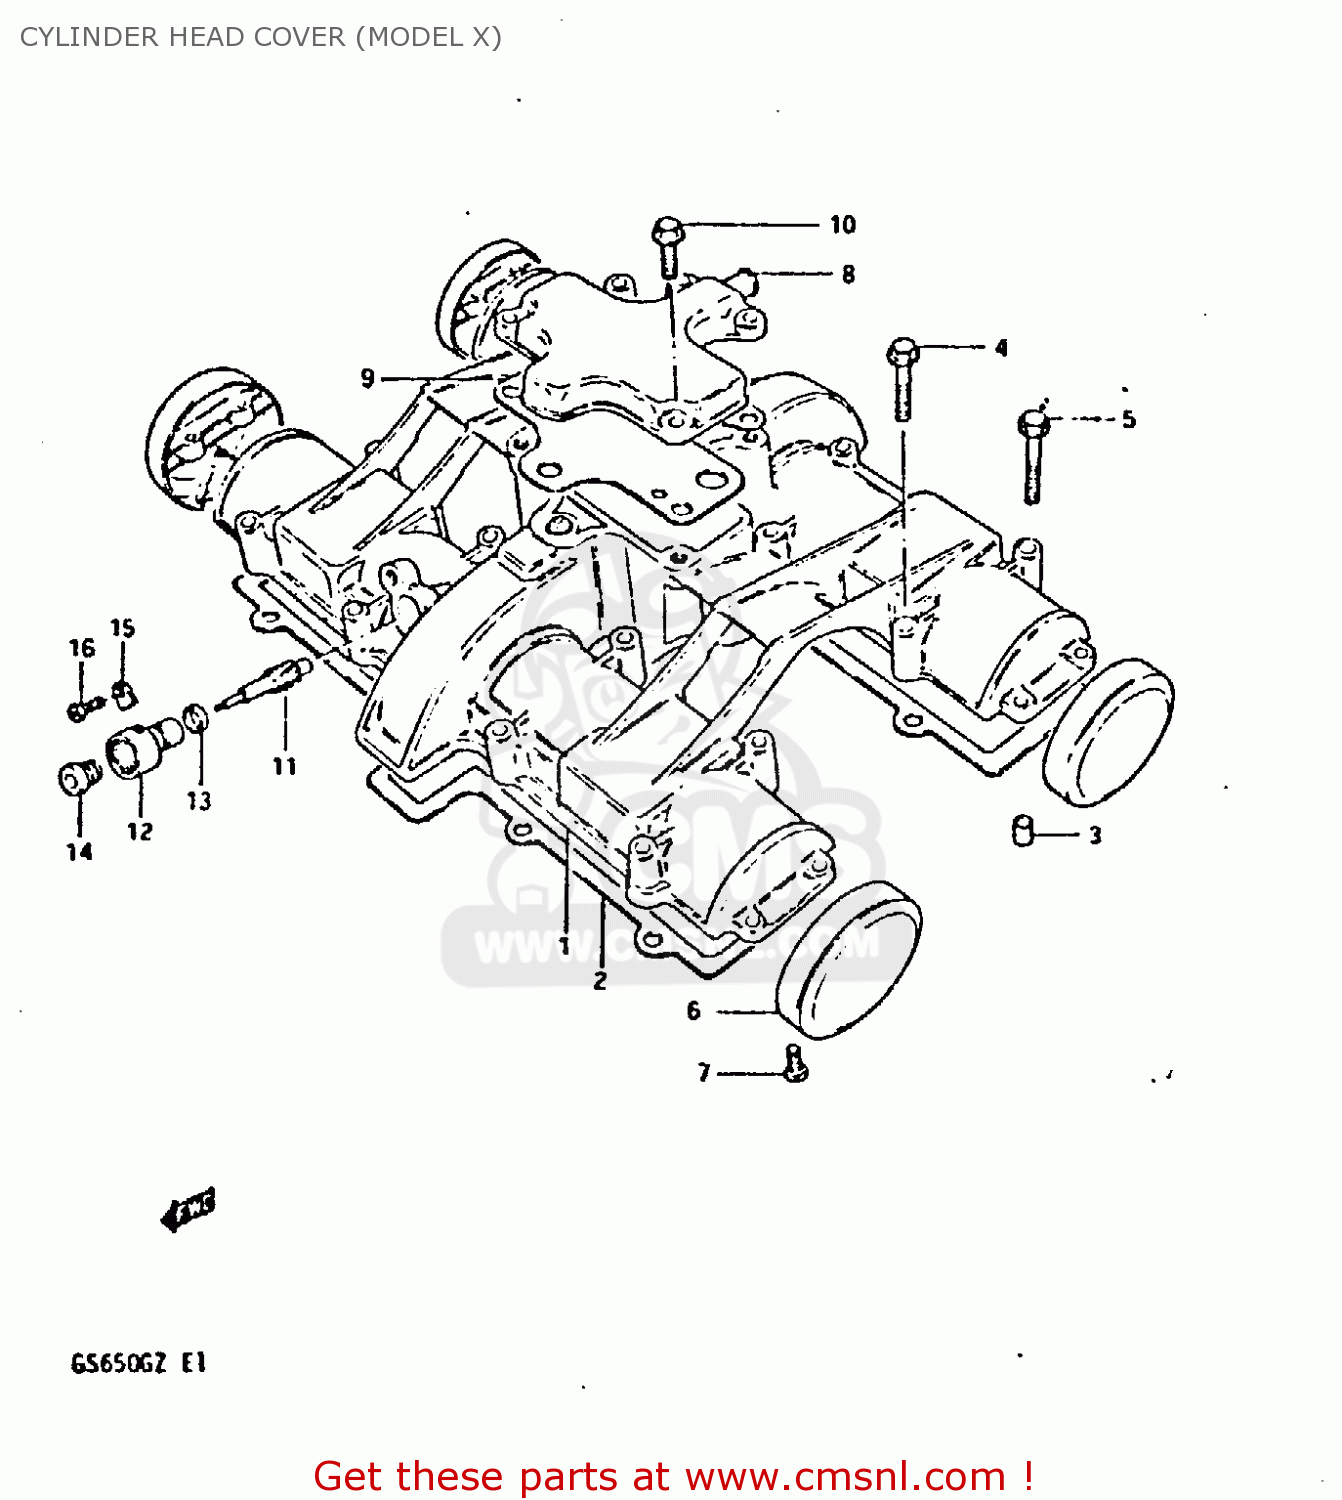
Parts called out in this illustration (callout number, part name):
1	COVER,CYLINDER HEAD
2	GASKET,CYLINDER HEAD COVER (MCA)
3	PIN(6.2X8X11)
4	BOLT
5	BOLT,UNDER
6	CAP,CYLINDER HEAD COVER
7	SCREW
8	COVER,BREATHER
9	GASKET (MCA)
10	BOLT,REAR
11	GEAR,TACHOMETER DRIVEN
12	SLEEVE,TACHOMETER DRIVE
13	SEAL,TACHOMETER DRIVEN
14	SEAL,OIL(5X12X8)
15	PLATE,TACH DRIVE GEAR SLEEVE
16	SCREW(5X12)
